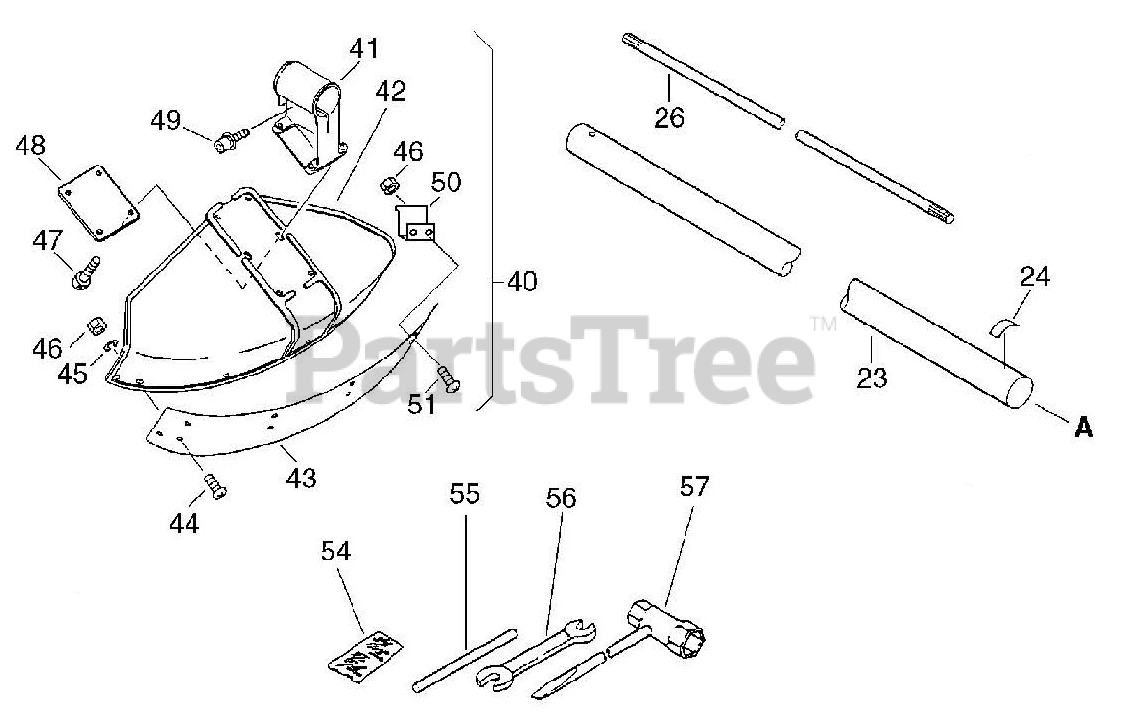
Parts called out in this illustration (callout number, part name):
23	MAIN PIPE ASSY
24	LABEL - ALIGNMENT
26	DRIVESHAFT
40	SHIELD ASSY
41	BRACKET, SHIELD
42	SHIELD, DEBRIS
43	EXTENSION, SHIELD
44	SCREW 5×18
45	WASHER 5.5×12×0.8
47	SCREW 5×14
48	BRACKET, SHIELD
49	BOLT - 5×25
50	CUTTER, LINE
51	SCREW 5×12
54	PIN, COTTER 2×22 (PKG. OF 10)
55	TOOL, LOCKING 5×120 MM
56	SPANNER 8×10
57	T-WRENCH 17×19 L200
